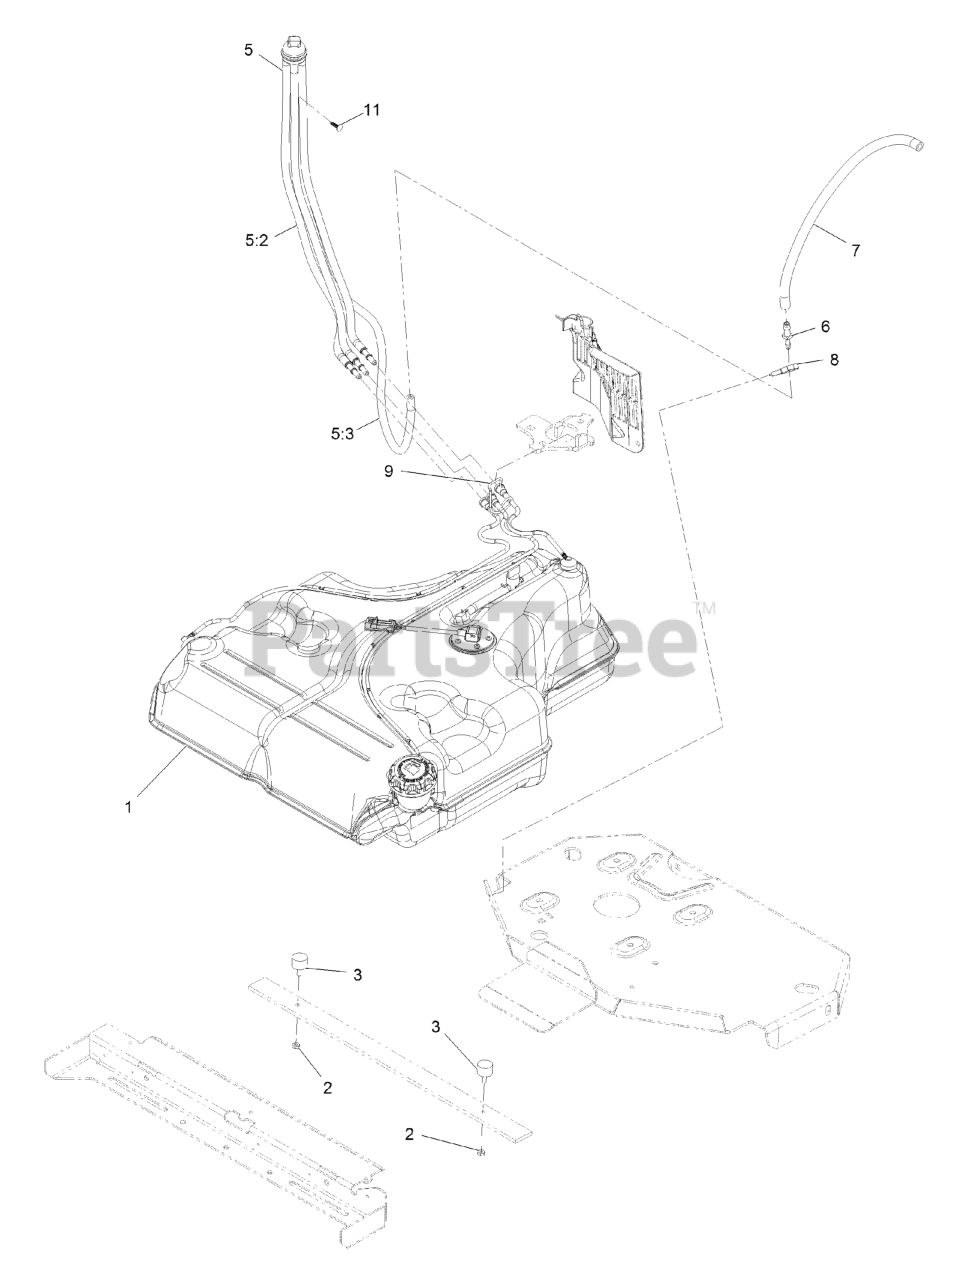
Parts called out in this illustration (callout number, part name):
1	FUEL TANK ASM
2	NUT-JAM
5	FUEL MANIFOLD VENT ASM
5:2	HOSE-FUEL
5:3	HOSE-FUEL
6	FITTING-STRAIGHT
7	HOSE-FUEL
8	CLAMP-HOSE
9	RETAINER-LINE, VAPOR
11	PLUG-PLASTIC
